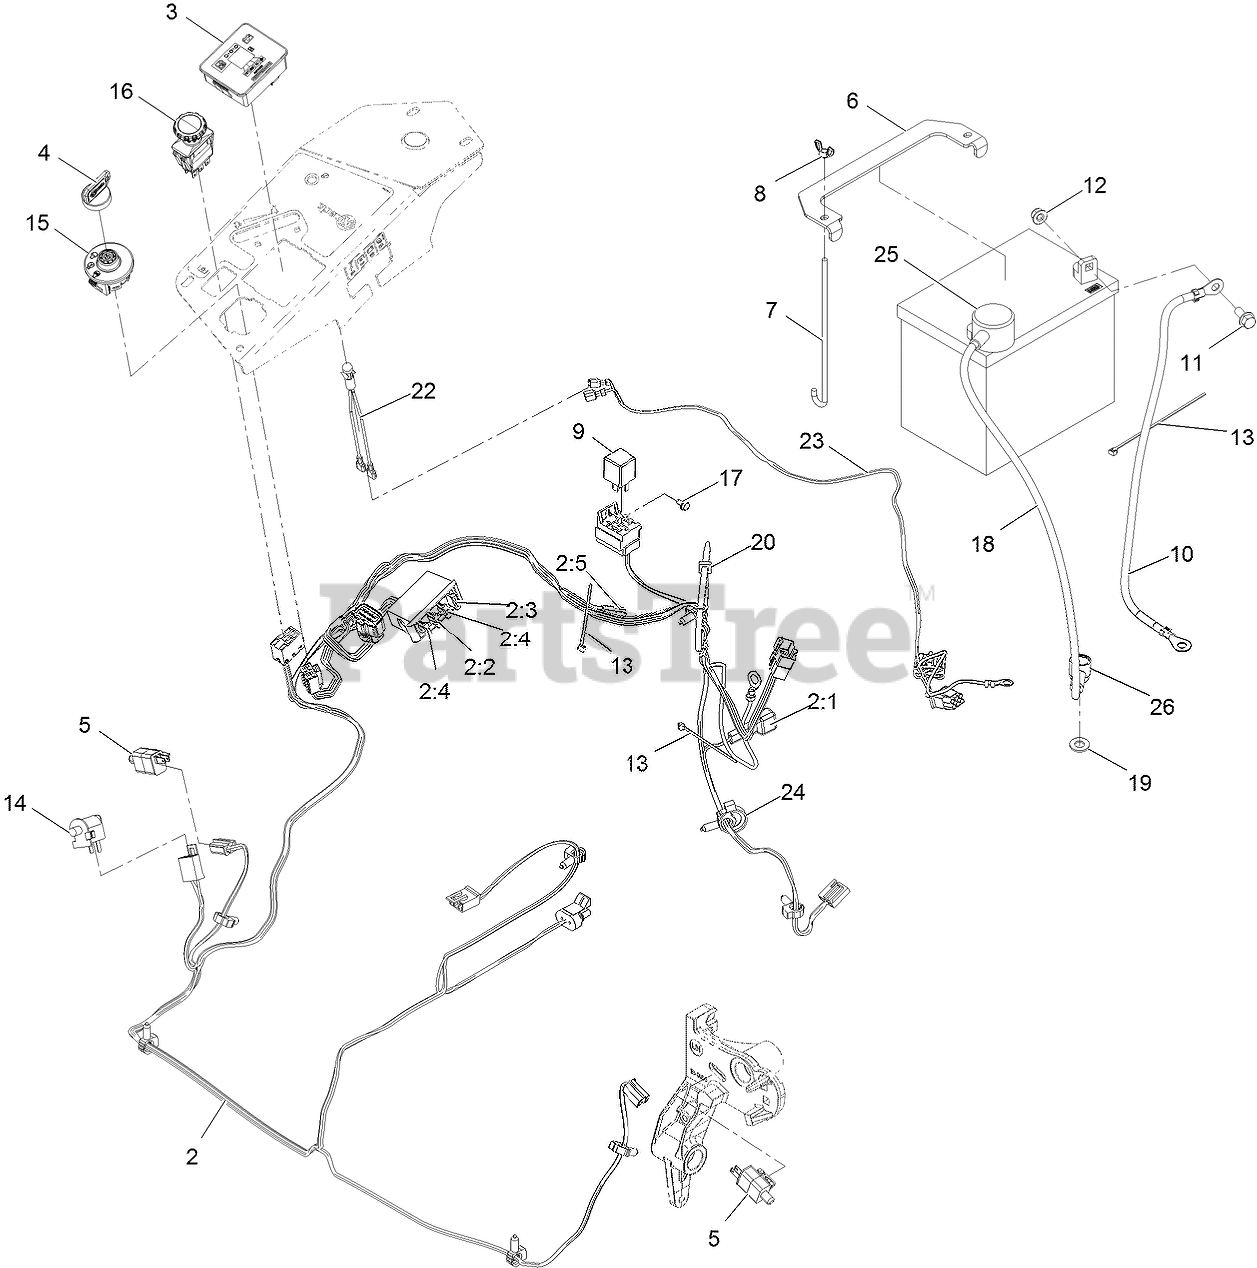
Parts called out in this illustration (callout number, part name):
2	HARNESS-WIRE, MAIN
2:2	FUSE-BLADE, 10 AMP
2:3	FUSE-BLADE, 15 AMP
2:4	FUSE-BLADE, 25 AMP
2:5	CAP-PLUG
3	FUEL/HOUR METER ASM
4	KEYS-IGNITION (SPARE PAIR
4	KEY-IGNITION
6	STRAP-TIE DOWN, BATTERY
7	BOLT-HOLDDOWN
8	WINGNUT
10	CABLE-BATTERY, NEGATIVE
11	SCREW-HHF
12	NUT-HF, NI
13	TIE-CABLE
14	SWITCH-BAIL
15	SWITCH-IGNITION
16	SWITCH-PTO, 10 AMP
17	SCREW-HWH
18	CABLE-BATTERY, POSITIVE
19	WASHER-FLAT
20	TIE-PLASTIC
22	INDICATOR-LED, RED
23	HARNESS-LIGHT, INDICATOR
24	CLAMP-HOSE
25	INSULATOR-BATTERY
26	INSULATOR-SOLENOID
